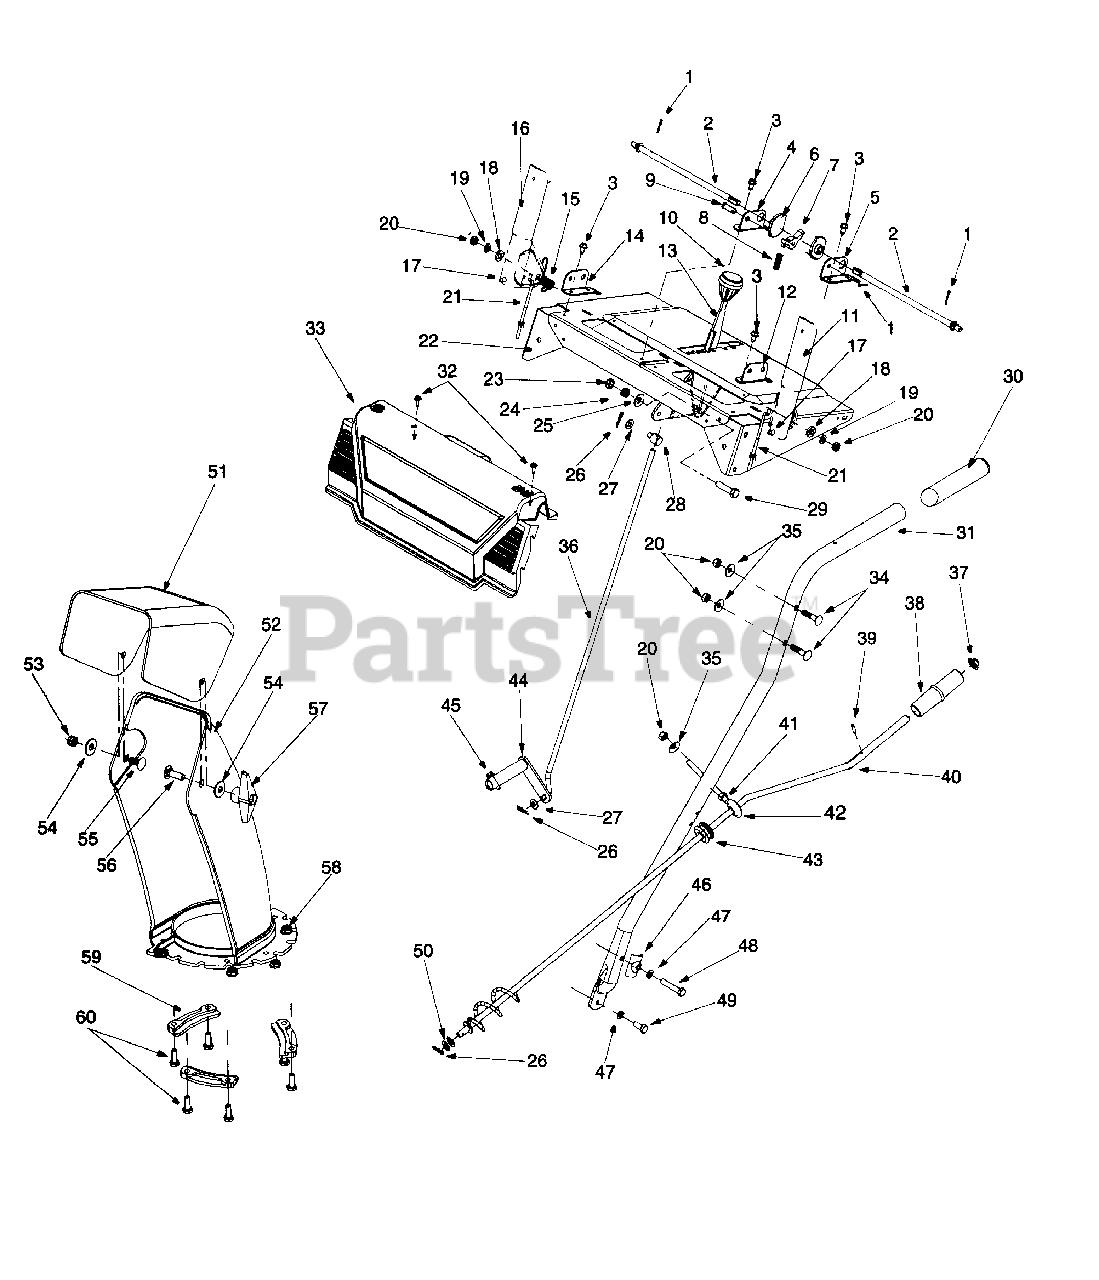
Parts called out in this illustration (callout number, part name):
1	Cotter Pin
3	Hex Washer Screw 1/4-20 x .5
6	Cam Lock Handle
7	Handle Lock Pawl
8	Compression Spring
9	Clevis Pin
10	Knob
11	Handle Assy - LH
15	Torsion Spring
16	Handle Assy - RH
17	Rubber Bumper
18	Washer
19	Lock Washer 5/16
20	Hex Nut 5/16-18
21	"Z" Fittings For Control Cables
24	Compression Spring
25	Bell Washer
26	Cotter Pin
27	Flat Washer 5/16
28	Ferrule
29	Hex Cap Screw 3/8-24 x 1.50
33	Handle Panel
34	Carriage Bolt 5/16-18 x 1.50
35	Bell Washer .340 ID x .872 OD
36	Shift Rod
37	Push Cap
38	Chute Knob
39	Roll Pin
40	Chute Crank
41	Hex Nut 5/16 - 18
42	Chute Crank Eyebolt
43	Rubber Grommet
45	Hex Washer Screw 1/4-20 x 1.0
46	Handle Tab
47	Lock Washer 5/16
48	Hex Cap Screw 5/16-18 x 1.75
49	Hex Cap Screw 5/16-18 x .75
50	Flat Washer
51	Upper Chute
52	Lower Chute
53	Hex Lock Nut 5/16-18
54	5/16 Washer
55	Carriage Bolt 5/16-18 x .75
56	Carriage Screw 5/16-18 x 1.0
58	Hex Lock Nut 1/4-20
59	Flange Keeper
60	Hex Cap Screw 1/4-20 x .75
